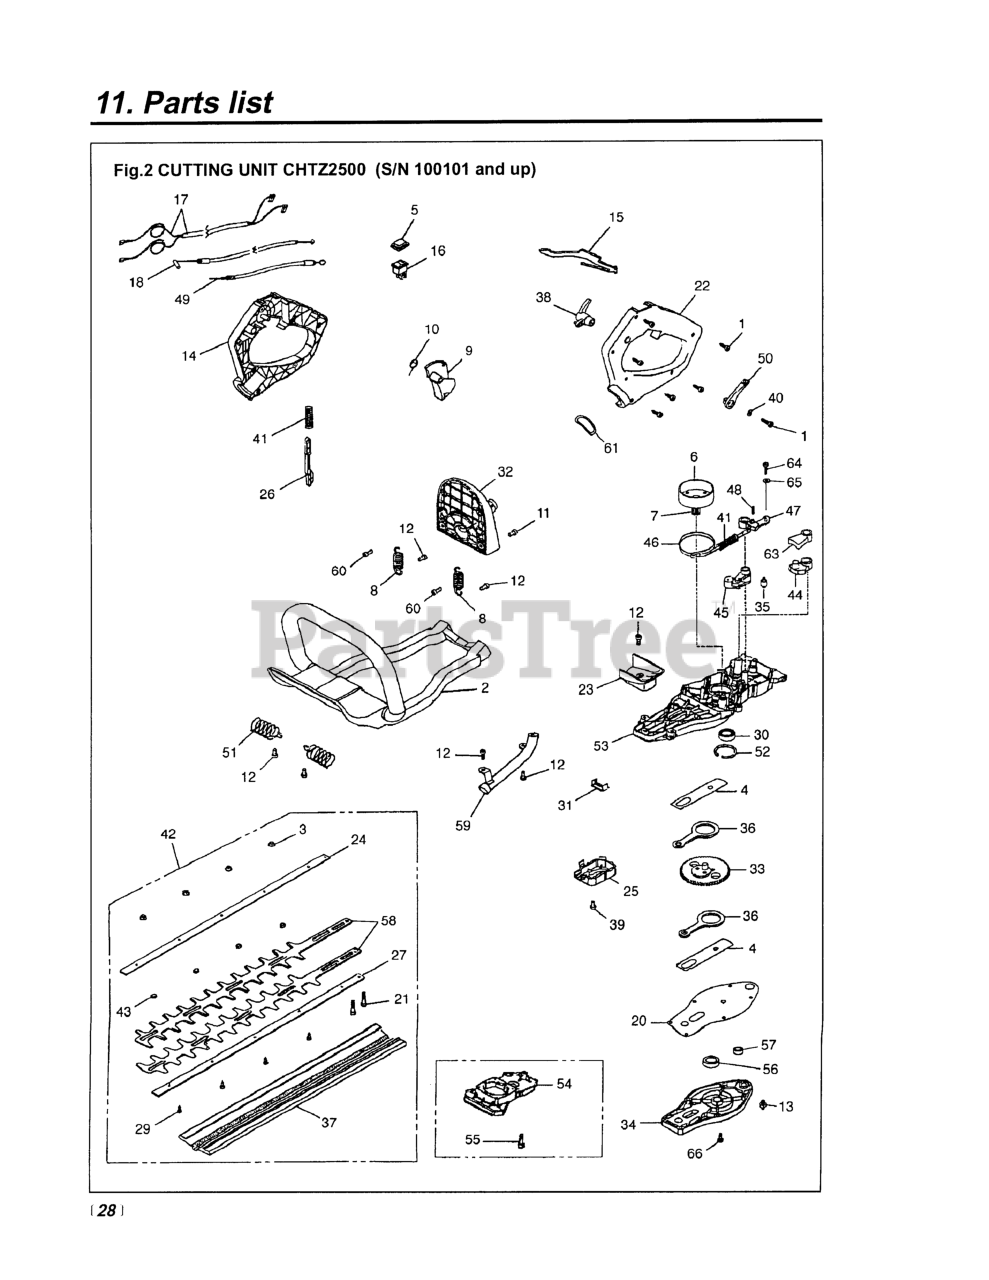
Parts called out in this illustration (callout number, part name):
1	SCREW (HANDLE)
3	NUT
4	PLATE
5	GUARD, SWITCH
6	DRUM, CLUTCH
7	GEAR, DRIVE (USE T4500-13110)
8	SPRING
9	LEVER, THROTTLE
10	SPRING
11	SCREW
12	SCREW
13	GREASE NIPPLE
14	HANDLE
15	LEVER
16	SWITCH (RPLS 2317011A)
17	SWITCH CABLE
18	CABLE, THROTTLE
20	GASKET
21	SCREW (HANDLE)
22	HANDLE, REAR
23	DEFLECTOR
24	SUPPORT, BLADE
26	ROD
27	GUIDE, BLADE
29	SCREW
30	BEARING
31	GASKET (USE 58040077A)
32	SUPPORT
34	COVER
35	ROLLER
37	GUARD, BLADE
38	LEVER
39	SCREW
40	WASHER
41	SPRING
43	SPACER
44	CAM, BRAKE
45	LEVER
46	BAND, BRAKE
47	LEVER, BAND
48	PIN
49	CABLE, THROTTLE
51	SPRING
52	RING, SNAP
53	CASE, GEAR (RPLS 58042021)
54	COVER, GEAR
55	SCREW TORX, M5X22
56	BEARING
57	BEARING
58	BLADE (REPLACES 58040043)
59	DEFLECTOR
60	SCREW
61	SPACER
63	LEVER
64	SCREW
65	WASHER
66	SCREW TORX, M5X22
